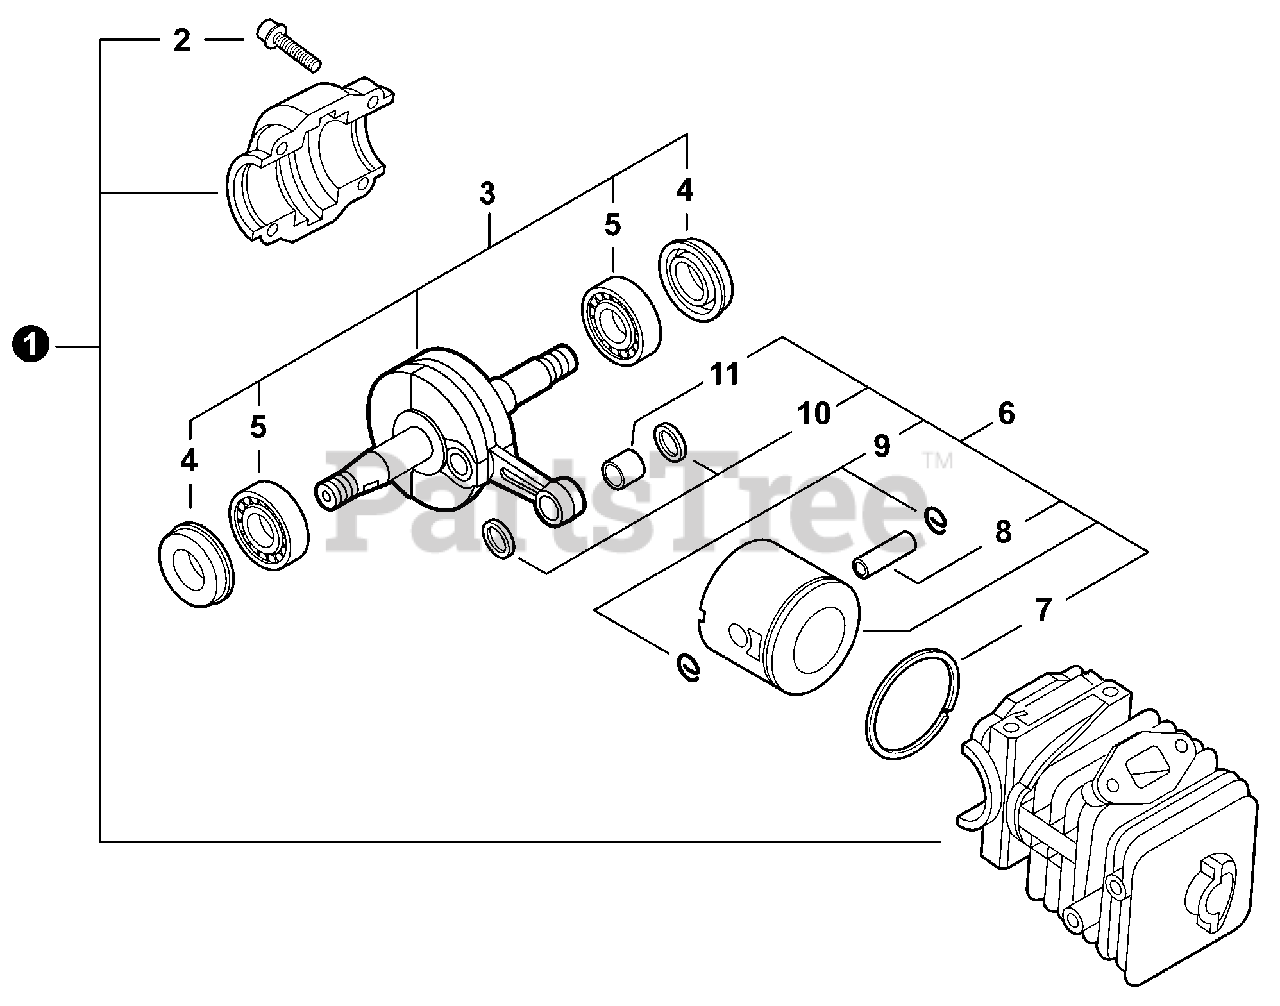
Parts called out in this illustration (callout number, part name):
1	CRANKCASE SET
2	BOLT 5×25
3	CRANKSHAFT ASSY
4	SEAL, OIL 12
5	BEARING, BALL - 6201 C3
6	PISTON KIT
7	RING, PISTON
8	PIN, PISTON
9	RING, SNAP
10	WASHER, THRUST
11	BEARING, NEEDLE 8
